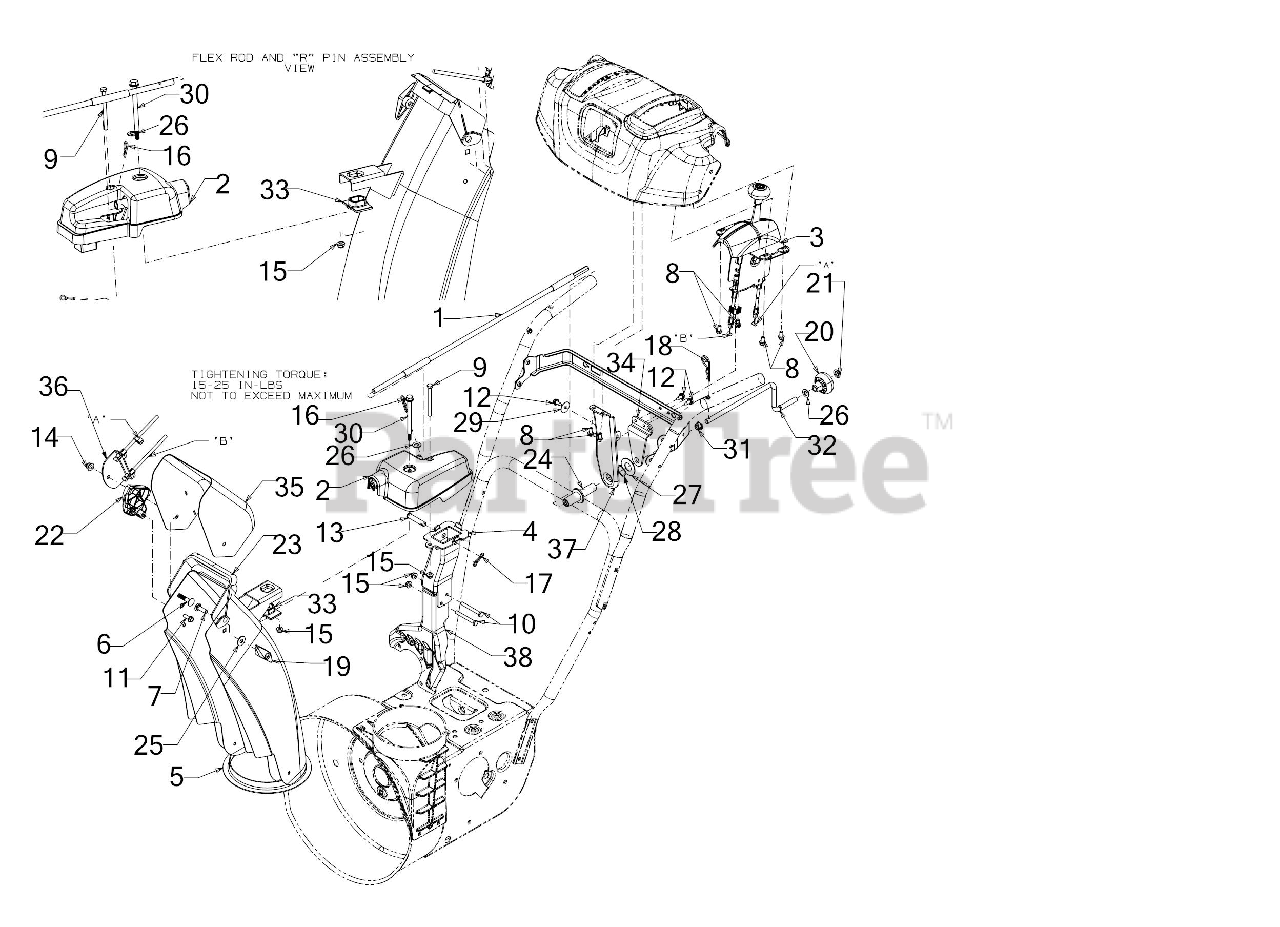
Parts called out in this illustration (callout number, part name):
1	CHUTE CONTROL SHAFT
2	WORM GEARBOX ASSEMBLY
3	2-WAY TALL CHUTE CONTROL ASSEMBLY
4	CHUTE MAST BRACKET
5	LOWER STEEL CHUTE 6" DIA
6	CARRIAGE BOLT 5/16-18 x 1.50
7	CARRIAGE BOLT 5/16-18 x 1.00
8	HEX SCREW 1/4-15 x .50
9	SCREW 1/4-20 x 3.0 GR5
10	SCREW 1/4-20 x 2.25 GR5
11	SCREW 1/4-15 x .750
12	SCREW 1/4-20X.625
13	CLEVIS PIN 3/8 x 1.87
14	FLANGE LOCK NUT 5/16-18
15	FLANGE LOCK NUT
16	INTERNAL COTTER PIN
17	BOW TIE COTTER PIN 1/4-5/16
18	INTERNAL COTTER PIN
19	WING NUT KNOB
20	SHIFT KNOB
21	PUSH NUT
22	CHUTE TILT GUIDE
23	UPPER CHUTE ADAPTER
24	CHUTE ROD COUPLER
25	FLAT WASHER
26	FLAT WASHER
27	FLAT WASHER
28	WAVE WASHER .785X1.00X.012
29	FLAT WASHER
30	SHOULDER SCREW
31	BUSHING .380 ID
33	HELICAL GEAR CHUTE ADAPTER
34	ROD SUPPORT BRACKET
35	UPPER CHUTE STEEL
36	CABLE BRACKET GUIDE
37	CHUTE CONTROL BRACKET
38	CHUTE SUPPORT BRACKET
